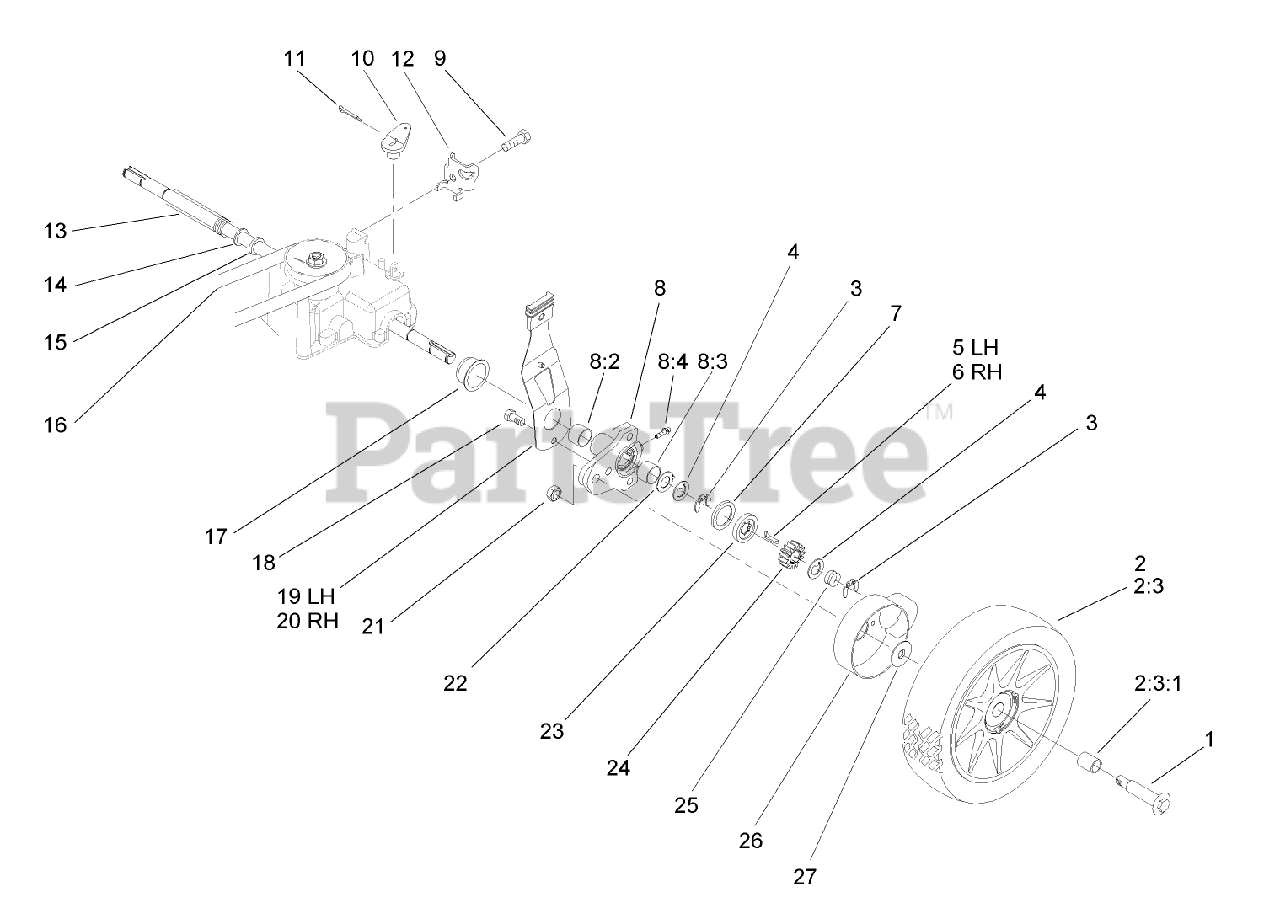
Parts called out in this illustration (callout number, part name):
1	BOLT-SHOULDER
2	WHEEL AND GEAR ASM
2:3	8 INCH WHEEL ASM
2:3:1	BUSHING
3	RING-CLIP, LOCKING
4	WASHER-THRUST, KEYED
5	KEY-ROCKING, LH
6	KEY-ROCKING, RH
7	RING-FRICTION
8	REAR HEIGHT ADJUSTMENT ARM ASM
8:2	BUSHING
8:3	BUSHING
8:4	FITTING-GREASE
9	SCREW-HWHTF
10	LEVER-SHIFT
11	PIN-COTTER
12	CLAMP-CABLE
13	COVER-SHAFT, DRIVE
14	WASHER
15	WASHER
16	V-BELT
17	RING-ISOLATOR
18	SCREW-HWH
19	LH REAR SPRING ARM ASM
20	RH REAR SPRING ARM ASM
22	WASHER-ARM, PIVOT
23	WASHER-CLUTCH
24	GEAR-PINION
25	SPRING-COMPRESSION
26	COVER-WHEEL
27	WASHER-STEPPED
